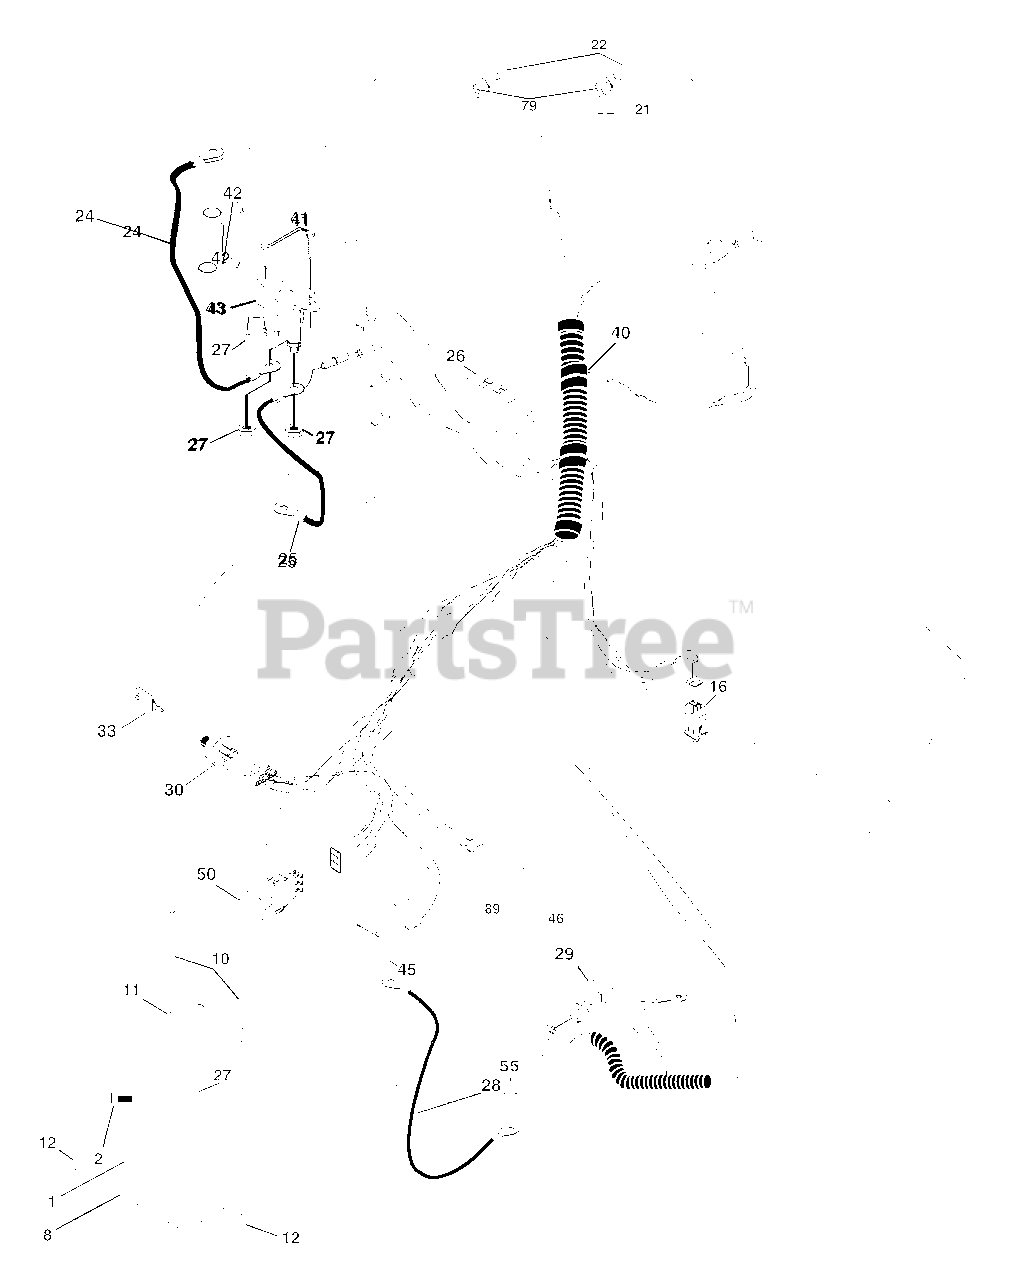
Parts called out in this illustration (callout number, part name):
1	Battery
2	Bolt Hex Hd 1/4-20 unc x 3/4
8	Tray, Battery
10	Bolt, BTR FRT 1/4-20 x 7.5
11	Hold Down Battery, Front
12	Nut, Push, Nylon
16	Switch Interlock Push-In
21	Harness Asm Light W/Bulbs
22	Bulb Light
24	Cable Battery
25	Cable Batterywire
26	Fuse
27	Nut Keps Hex 1/4-20 unc
28	Cable Ground
29	Switch Plunger Normal NC Gray
30	Switch Ign 4 pos w/lights
33	Key Ign
40	Harness Ign.
41	Bolt Blk Fin Hex 1/4-20 x 1/2
42	Cover Terminal Red
43	Solenoid
45	Ammeter Rectangular
46	Hourmeter Snap-In
50	Switch, PTO
55	Screw Thdrol 5/16-18 x 1/2
79	Bulbholder
89	Bracket Snap-In Hourmeter
